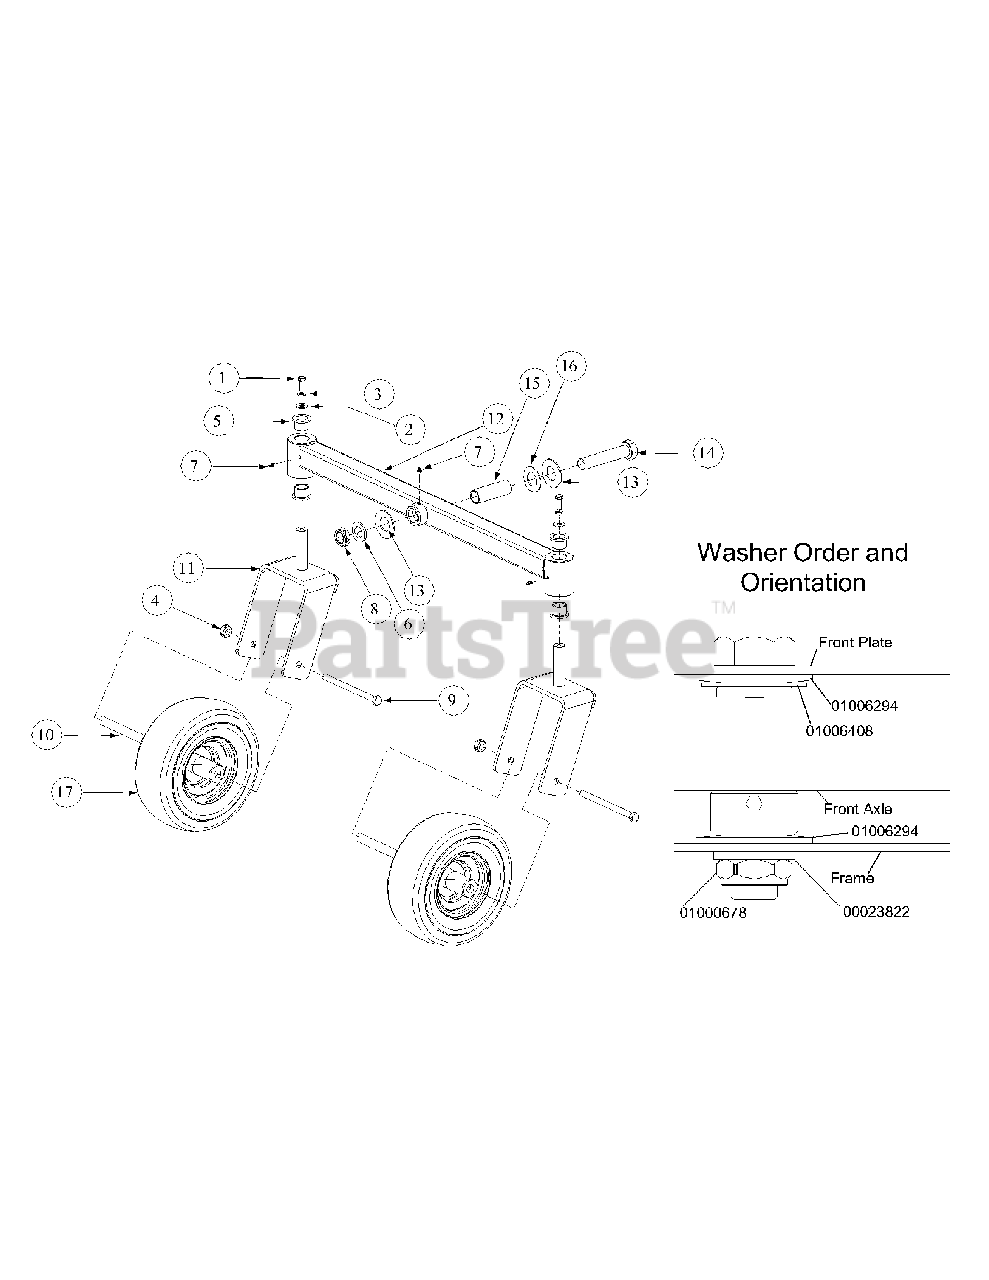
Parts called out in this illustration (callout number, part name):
1	Hex Cap Screw, 3/8-16, x 1
2	Flat Washer, .411 x 1.25 x 1.00
3	Lock Washer, 3/8
4	Center Lock Nut, 1/2-20
5	Flange Bearing, 1.013
6	Special Washer
7	Grease Fitting, 1/4-28 x 3/16
8	Jam Lock Nut, 1.0-14
9	Hex Cap Screw, 1/2-20 x 7.00
10	Spacer, .51 ID x .75 OD x 5.83 Lg
11	Caster Wheel Bracket Assembly
12	Narrow Front Axle Assembly
13	Belle Washer, 1.25 ID x 2.500 OD x .1
14	Hex Cap Screw, 1-14 x 5.0
15	Spacer, 1.005 ID x 1.25 OD x 3.6
16	Flat Washer, 1.25 ID x 2.25 OD x .075
17	Wheel Assembly, 11 x 4-5.00
